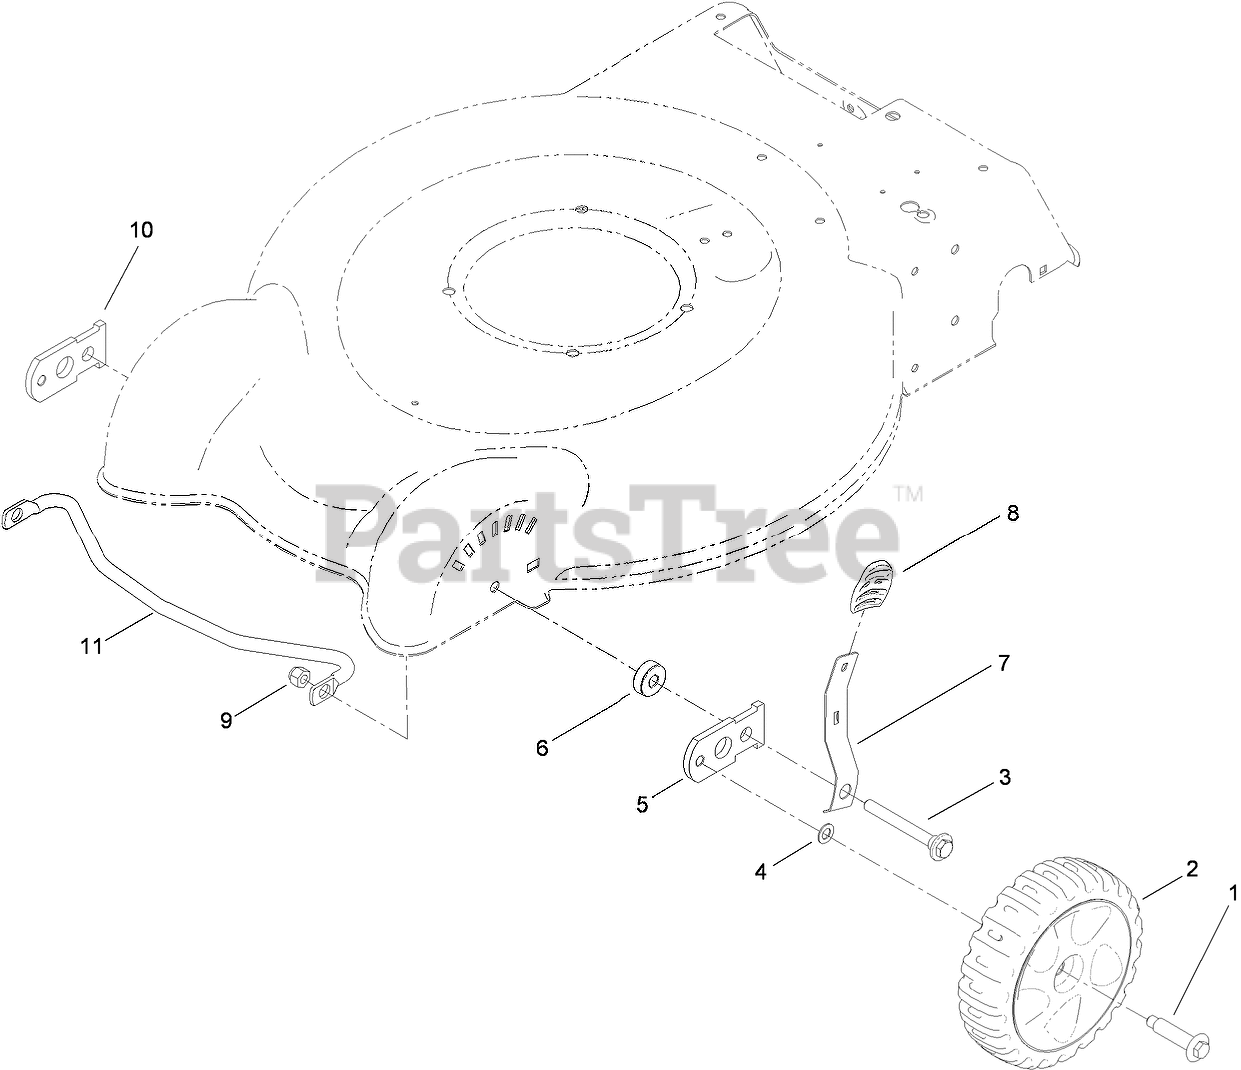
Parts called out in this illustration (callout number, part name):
1	BOLT-SHOULDER
2	7 INCH WHEEL AND TIRE ASM
3	BOLT-SHOULDER
4	WASHER
5	ARM-PIVOT, RH
6	SPACER-ARM, PIVOT
7	ARM-SPRING, FRONT
8	Knob-Lever, HOC
9	NUT-LOCK, NI
10	ARM-PIVOT, LH
11	BRACE-FRONT
